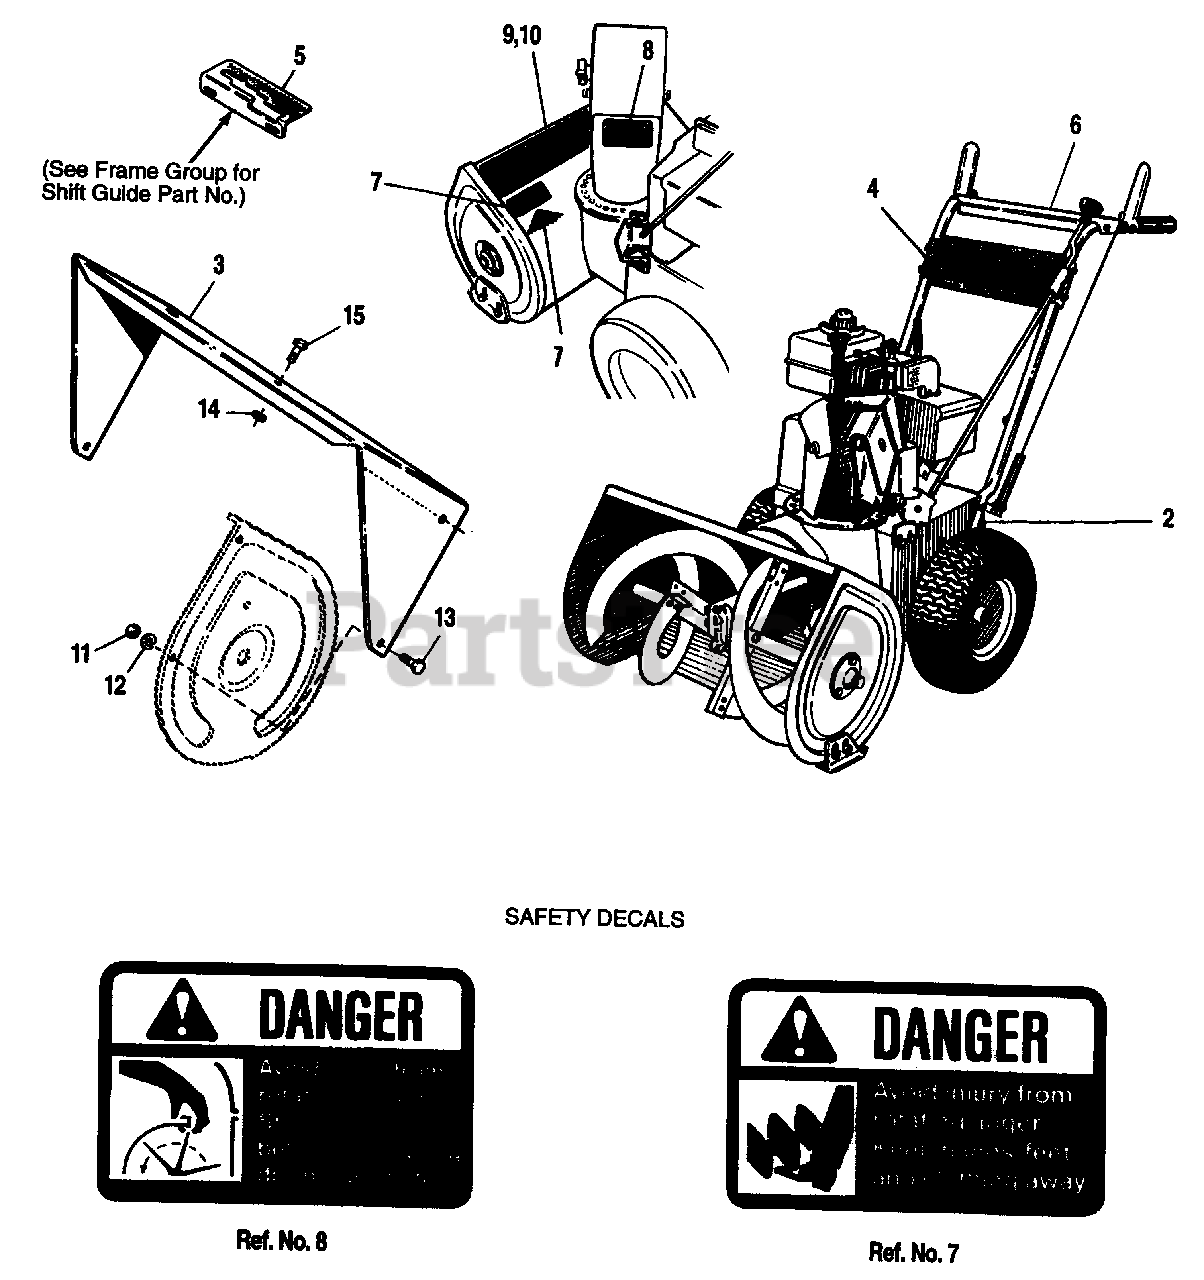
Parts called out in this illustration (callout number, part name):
1	DECAL, OPEI
2	ID. PLATE, Simplicity
3	WRAPPER EXT
4	DECAL, Simplicity
5	DECAL, Shift pattern
6	DECAL, Dash
7	DECAL, Danger, Auger
8	DECAL, Danger, Blower
9	DECAL, Simplicity 755
10	DECAL, Simplicity 555
11	NUT, Hex, 1/4-20
12	LOCKWASHER, 1/4
13	CAPSCREW, 1/4-20 x 1/2
14	NUT, Hex, Flange, 1/4-20
15	CAPSCREW, 5/16-18 x 5/8
